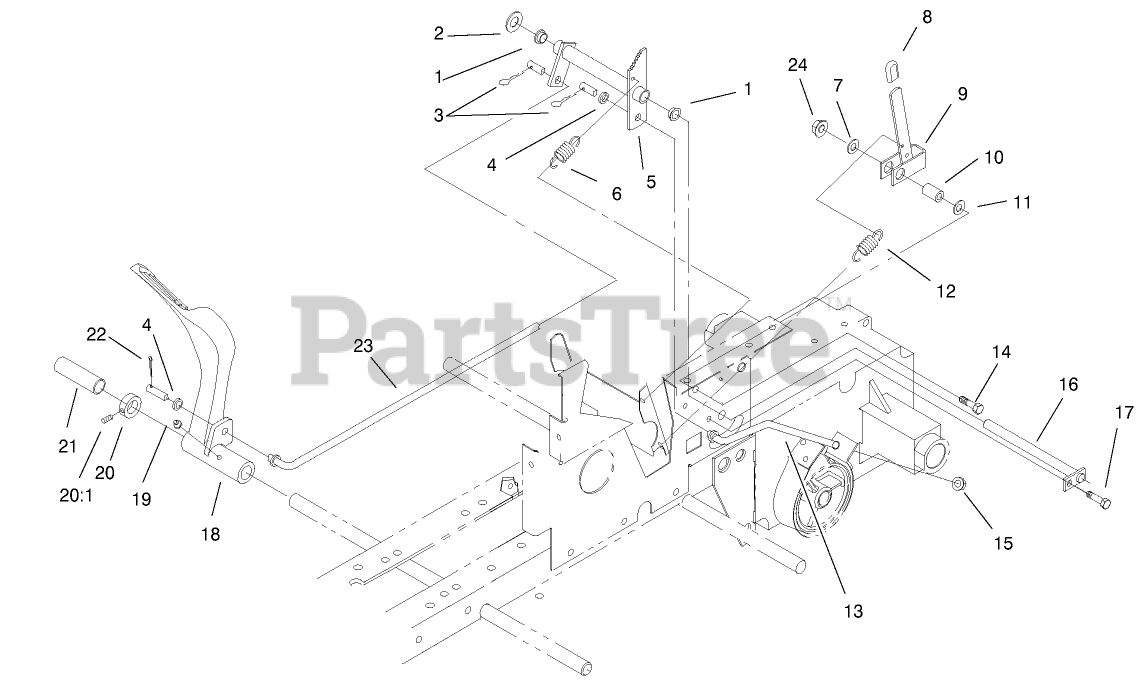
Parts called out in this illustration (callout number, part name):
1	BUSHING-FLANGED
2	WASHER-FLAT
3	PIN-HAIR
4	WASHER-NYLON
5	BELCRANK ASM
6	SPRING-EXTENSION
7	WASHER-FLAT
8	GRIP
9	BRAKE LEVER ASM
10	SPACER
11	WASHER-FLAT
12	SPRING-BRAKE
13	ROD-REAR BRAKE
14	SCREW-HH
15	NUT-LOCK, NI
16	ROD ASM
17	SCREW-HWHTF
18	PEDAL-BRAKE, GEAR
19	FITTING-GREASE
20	COLLAR
20:1	SCREW-HSH
21	SLEEVE-PROTECTIVE
22	PIN-COTTER
23	ROD-BRAKE
24	NUT-LOCK, NI
